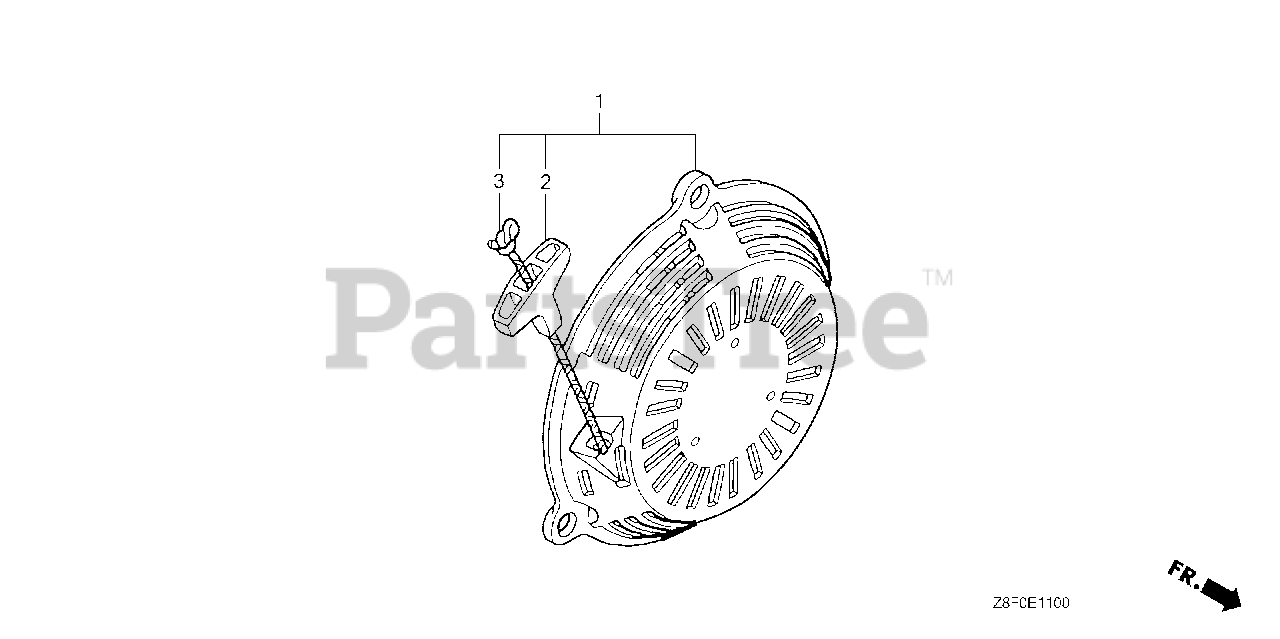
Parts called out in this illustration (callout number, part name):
1	STARTER ASSY., RECOIL *NH1* (BLACK)
1	STARTER ASSY., RECOIL *R280* (POWER RED)
2	KNOB, RECOIL STARTER
3	ROPE, RECOIL STARTER (#3.5X52")
